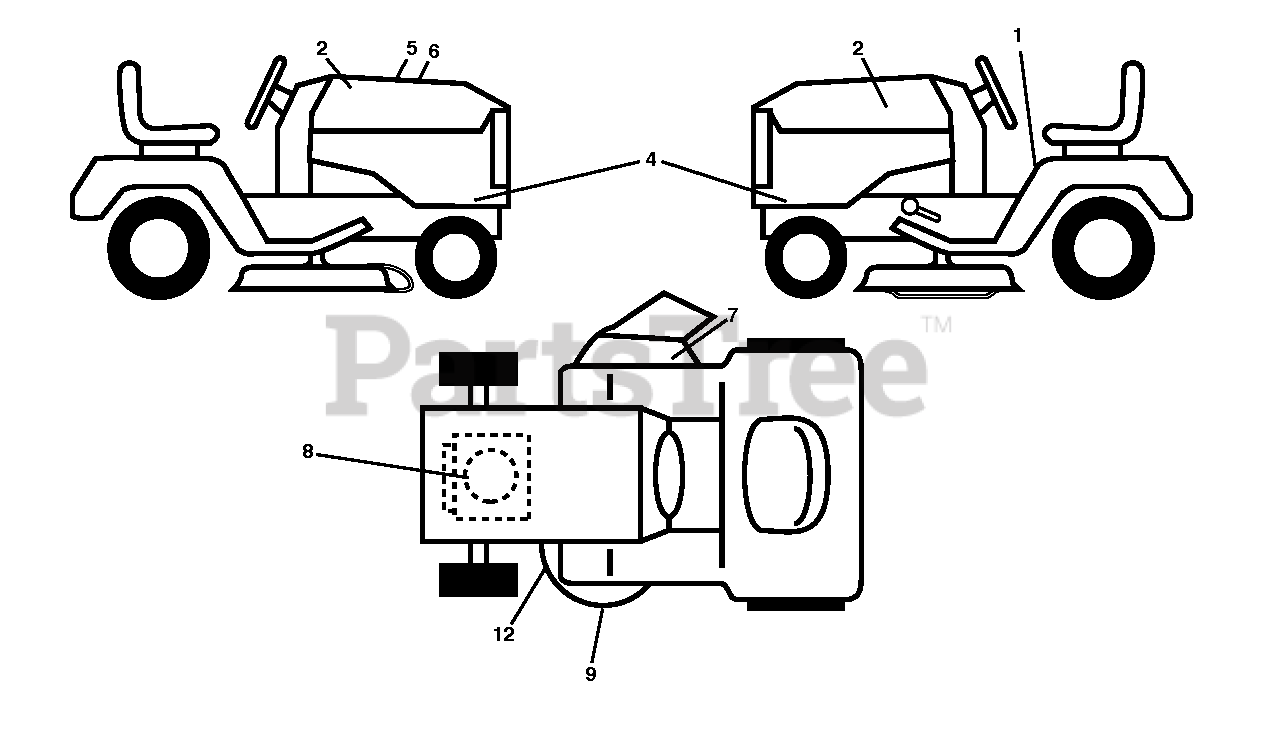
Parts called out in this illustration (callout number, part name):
1	DECAL.FENDER.WARNING.ENGLISH
2	Decal, WB 178MM 15 Husqvarna NEWBRAN
4	DECAL SIDEPANEL
5	DECAL.WARNING.CUST.RESP.E85.
6	Decal, Replacement BSM33 INTK TLW
7	DECAL, DECK DEFLECTOR, WARNING
8	DECAL.ENG.BS.18.5INTK.381713
12	DECAL.V-BELT.SCH.42/46"MEC/ELE
